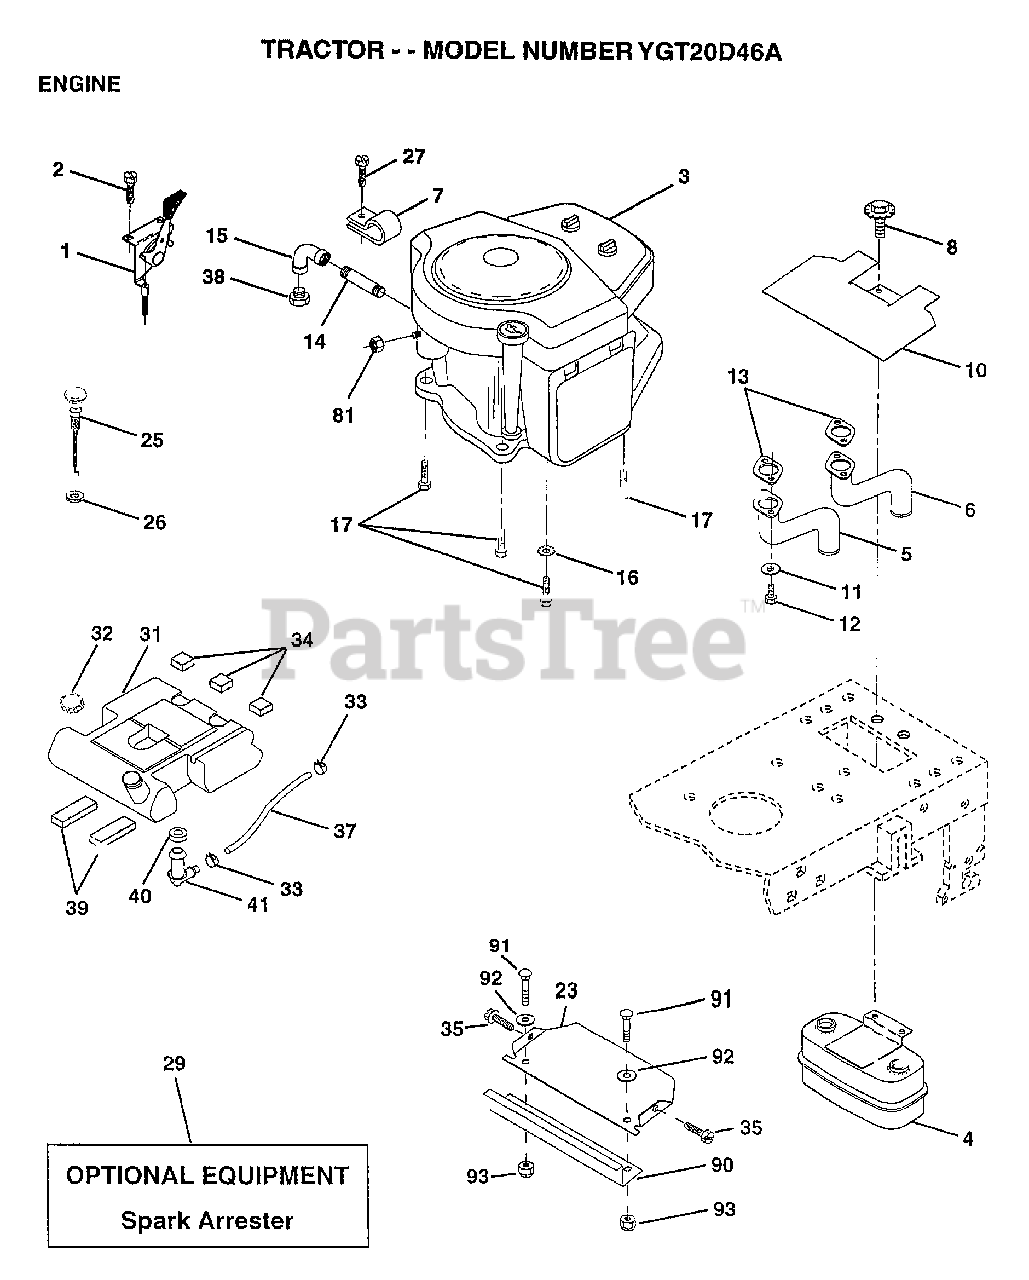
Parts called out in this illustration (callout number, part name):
2	SCREW LT
4	MUFFLER.TW.LOTONE
5	EXHAUST.B&S.18.LH
6	EXHAUST.B&S.18.RH
7	CLAMP.TUBE.DBL.EN
8	BOLT.5/16-18.UNC
10	SHIELD.HEAT.
11	LOCKWASHER
13	GASKET MUFFLER
14	PIPE NIPPLE LT
15	ELBOW
16	LOCKWASHER
17	SCREW LT
23	SHIELD-HEAT
25	"CONTROL.CHOKE.51"""
26	"NUT,KEPS 3/8-24IM"
27	"SCREW-TT,10-32 FL"
31	TANK FUEL REAR
32	CAP ASM FUEL
33	HOSE CLAMP
34	PAD-SPACER LT
35	SCREW
37	FUEL LINE T
39	PAD IDLER TI
40	BUSHING OUTLET T
41	STEM.TANK.FUEL
81	NUT
90	GUARD-DEBRIS
91	BOLT HXHD FIN
92	WASHER
